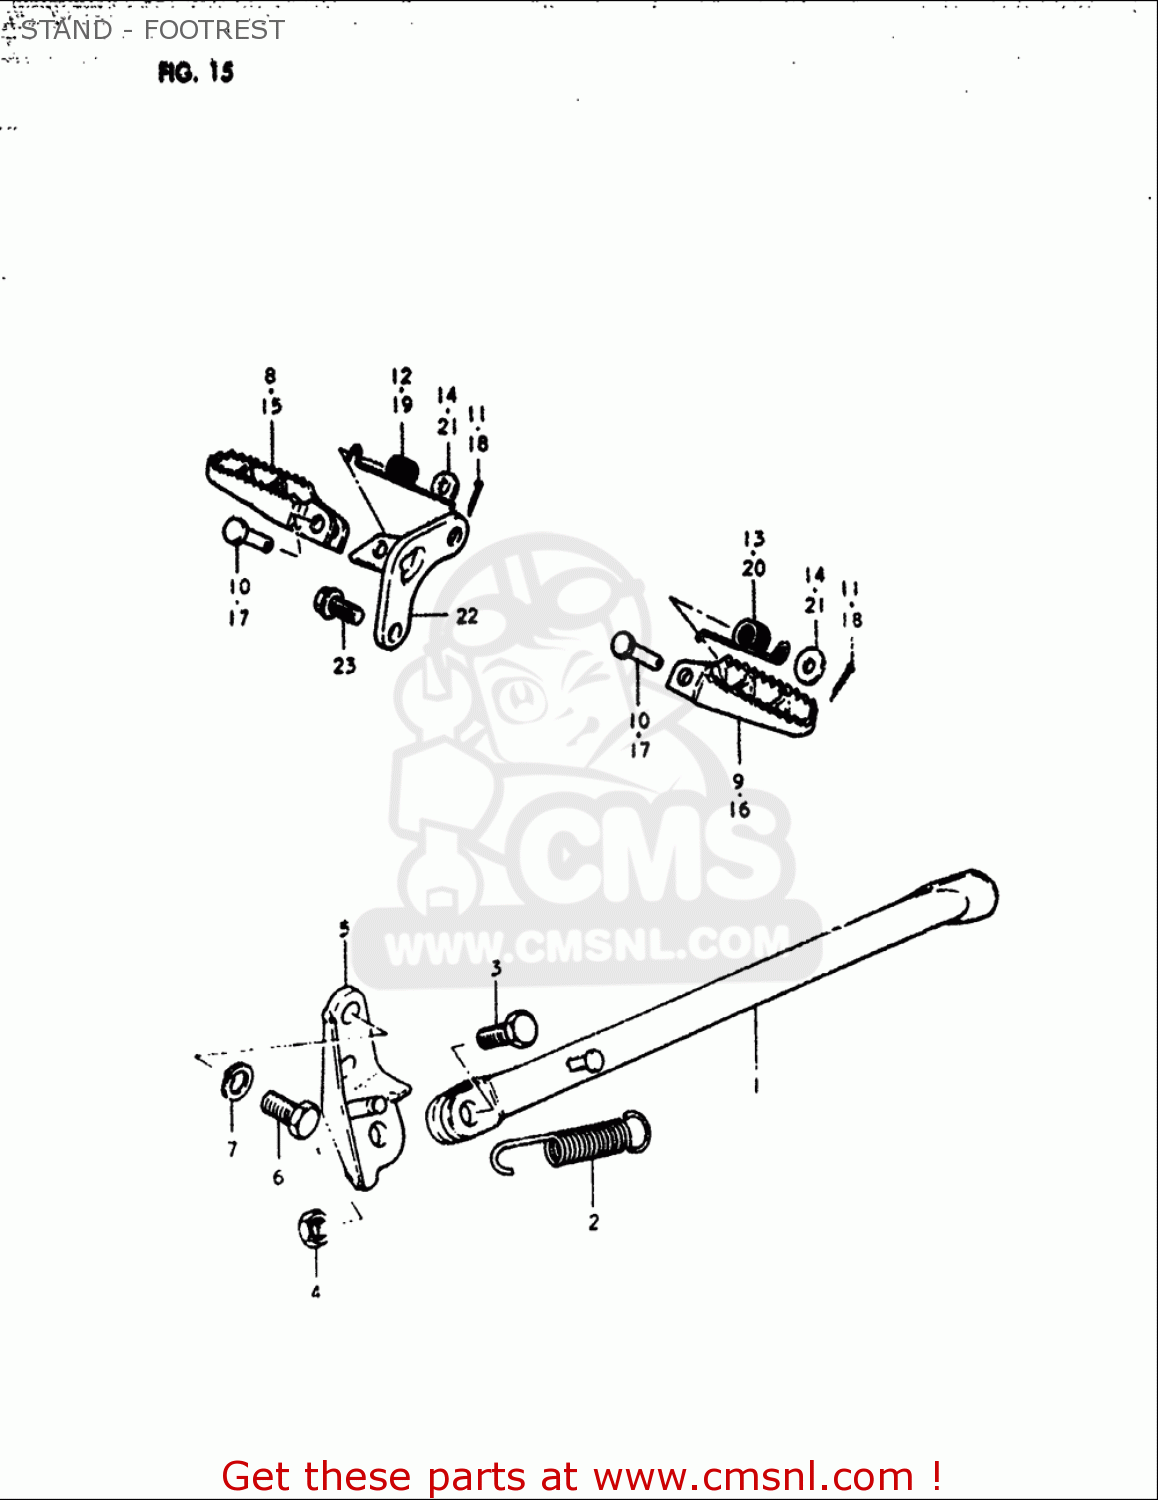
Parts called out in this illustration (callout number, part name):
1	STAND,SIDE
2	SPRING
3	BOLT(10X30)
4	NUT
5	BRACKET,PROP STAND
6	BOLT(10X19)
7	WASHER,LOCK
8	FOOTREST,FR,R
9	FOOTREST,FR,L
11	PIN
13	SPRING
14	WASHER
15	FOOTREST,FR,R
16	FOOTREST,FR,L
17	PIN
18	PIN 30X20
19	SPRING
21	WASHER
23	BOLT(10X20)
